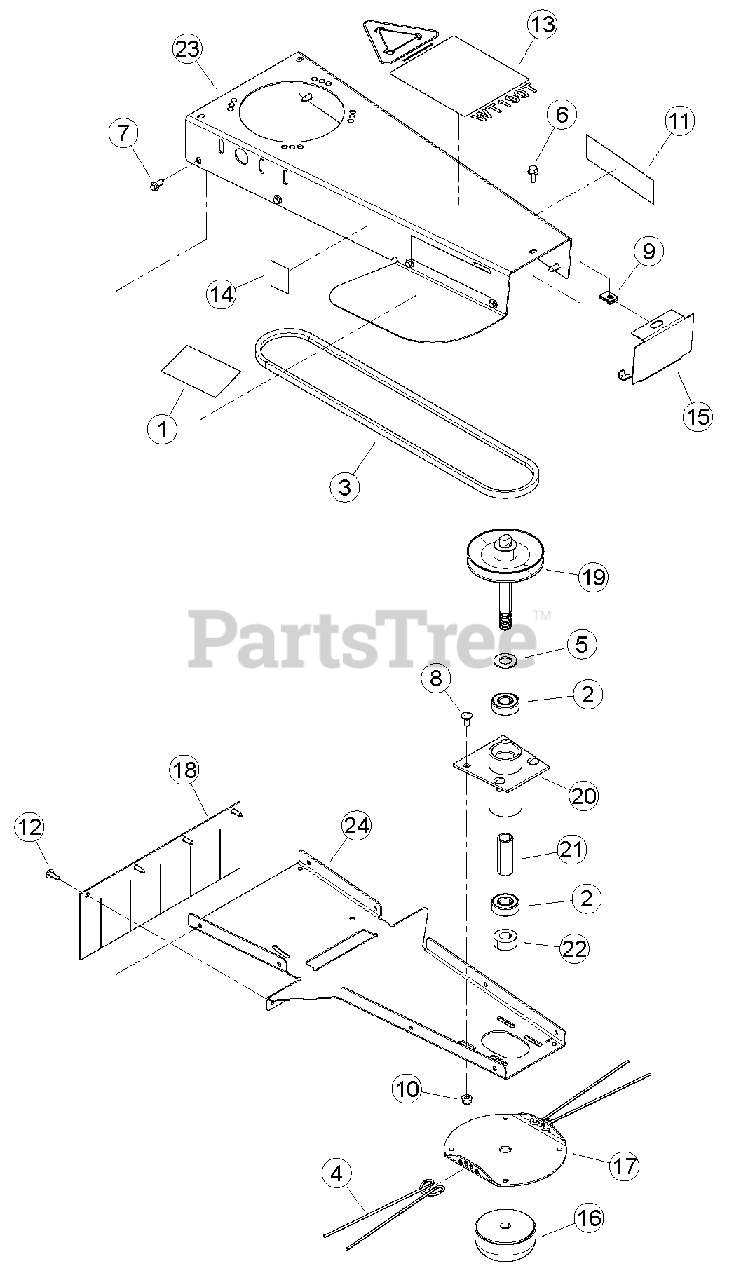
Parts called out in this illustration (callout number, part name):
1	DECAL, GRINDER DANGER
2	BEARING, 3/4 BALL
3	BELT, 4L53 ARAMID
4	STRING, .155 X 20-1/2
5	WASHER, 3/4" SAE FLAT ZP
6	BOLT, 5/16 X 3/4 FLANGE NC
7	SCREW, 11/32-12 X 7/8 HWH T-AB
8	BOLT, 5/16 X 3/4 GR5 CRG NC ZP
9	NUT, 5/16"-18 TINNERMAN U-TYPE
10	NUT, 5/16-18 NYLOCK-FLANGE
11	DECAL, ECHO BEARCAT 6.82 X 1.90
12	RIVET, PLASTIC .28 X 1"
13	DECAL, WT190T INFORMATION
14	DECAL, ECHO BEARCAT QR CODE
15	COVER, FRONT TRIMMER
16	WELDMENT, TRIMMER HEAD (HEAT TREAT)
17	DISK, TRIMMER HEAD
18	FLAP, TRIMMER
19	WELDMENT, TRIMMER PULLEY
20	WELDMENT, SPINDLE HUB
21	SPACER, TRIMMER SPINDLE
22	SPACER, TRIMMER HEAD
23	WELDMENT, TRIMMER BODY
24	BOTTOM, TRIMMER FRAME
